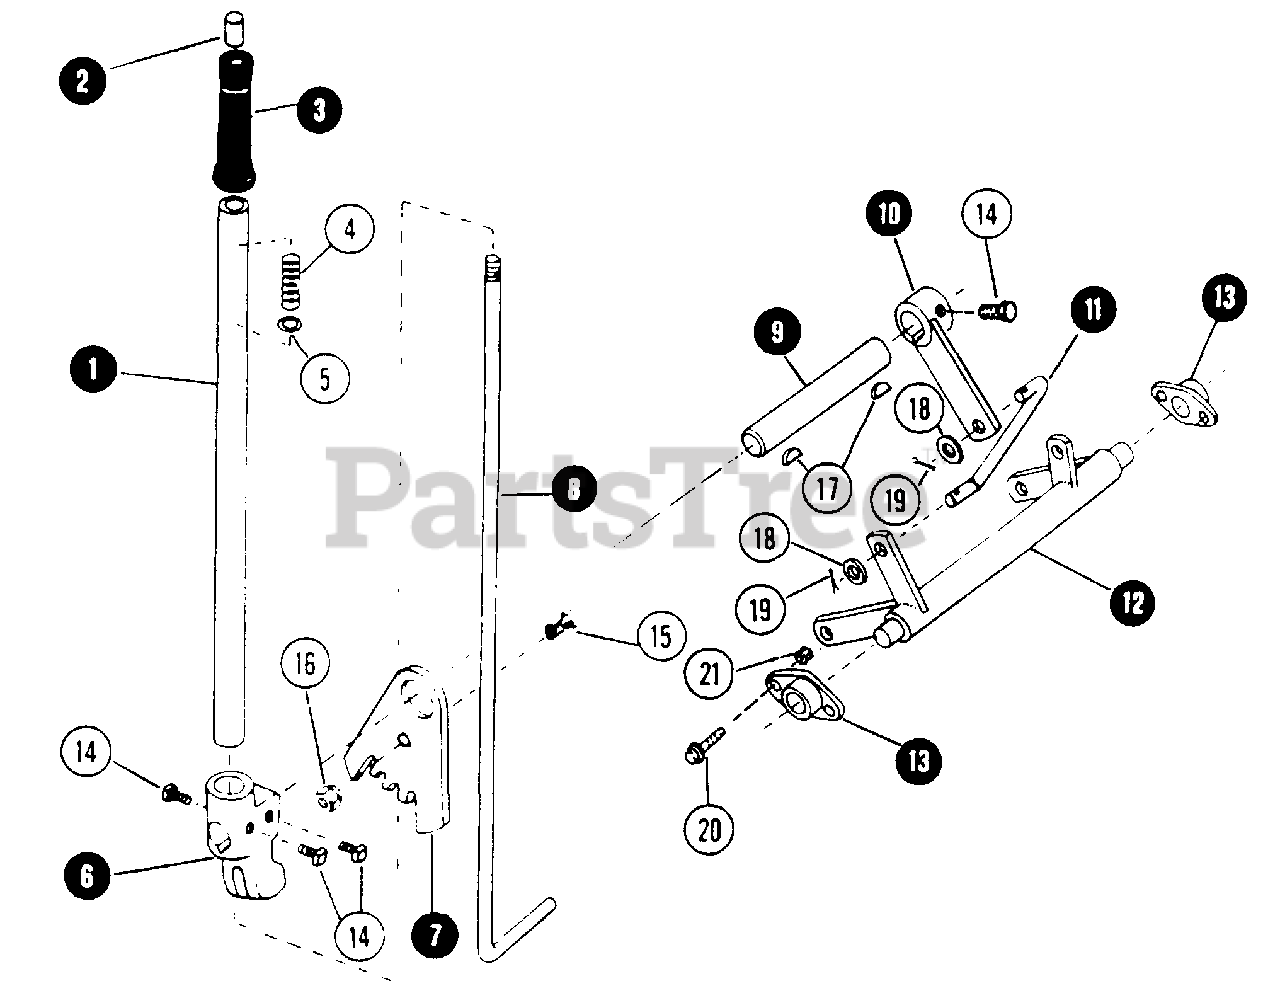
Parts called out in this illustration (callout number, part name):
1	LEVER, IMPLEMENT LIFT
2	BUTTON, LIFT LEVER ROD
3	GRIP, LIFT LEVER HANDLE
4	SPRING, LIFT LEVER ROD
5	WASHER, 9/32 x 1/2 x 3/64
6	SUPPORT, LIFT ARM
7	SECTOR, LIFT LEVER
8	ROD, LIFT LEVER
9	SHAFT, LIFT ARM
10	ARM, IMPLEMENT LIFT
11	ROD, LIFT SHAFT TO ARM
12	SHAFT, IMPLEMENT LIFT
13	BEARING, LIFT SHAFT
14	SCREW, 3/8 x 5/8 SQUARE HEAD SET
15	BOLT, (SPECIAL)
16	NUT, (SPECIAL)
17	KEY, LIFT ARM TO SHAFT
18	WASHER, 1/2 FLAT
19	COTTER-PIN, 5/32 x 1
20	BOLT, 3/8C x 1 FLANGE
21	NUT, 3/8C FLANGE LOCK
